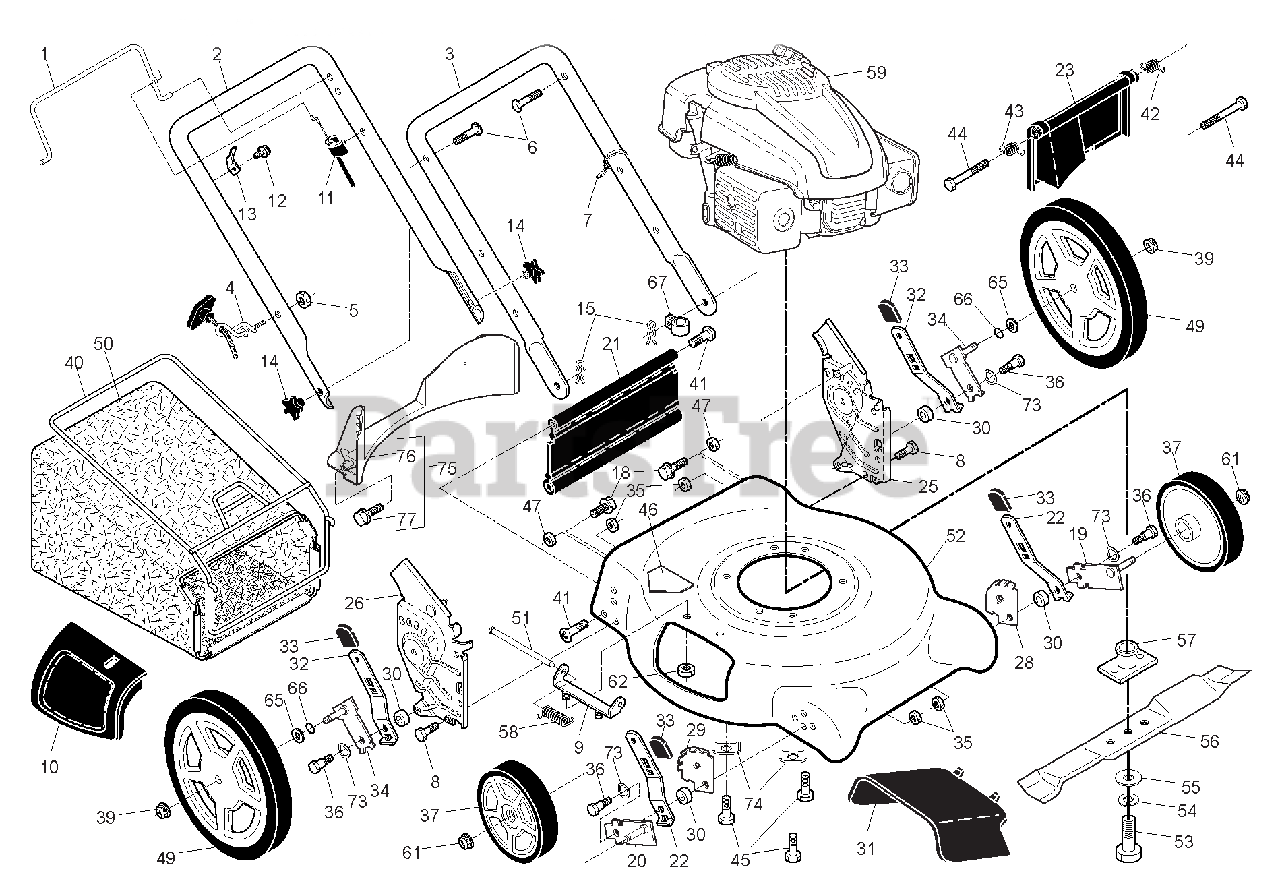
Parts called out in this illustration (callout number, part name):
1	Control Bar
2	Upper Handle
3	Lower Handle
4	Rope Guide
5	Nut, Hex
6	Handle Bolt
7	Wire Tie
8	Bolt, Hex Head 5/16-18 x 3/4
9	Hinge Bracket
10	Mulcher Door
11	Engine Zone Control Cable
12	Hex Washer Head Screw
13	UP-STOP BRACKET
14	Handle Knob
15	Hairpin Cotter
18	SCREW.HEX.WASHEAD.1/4-20 X 3/8
19	Axle Arm Assembly, Front, LH
20	Axle Arm Assembly, Front, RH
21	Kit, Rear Skirt
22	Selector Spring, Front
23	Rear Door Assembly
25	Handle Bracket Assembly, LH
26	Handle Bracket Assembly, RH
28	Wheel Adjusting Bracket, LH
29	Wheel Adjusting Bracket, RH
31	Discharge Deflector
32	Selector Spring, Rear
33	Selector Knob
34	Axle Arm Assembly, Rear, LH
35	Locknut, Hex 5/16-18
36	Shoulder Bolt
37	Wheel & Tire Assembly, Front
39	Flanged Locknut, Hex
40	Frame, Grassbag
41	Hinge Screw
42	Spring, Rear Door, LH
43	Spring, Rear Door, RH
44	Bolt, Rear Door
45	Screw, Hex Head, Threaded, Rol
46	Danger Decal
47	Nut, Hex
48	Axle Arm Assembly, Rear, RH
49	Wheel & Tire Assembly, Rear
50	Grassbag
51	Hinge Rod
52	Kit, Lawn Mower Housing (Inclu
53	Screw, Hex Head, Grade 8 3/8-2
54	Helical Lockwasher
55	Hardened Washer
56	21" Blade
57	Blade Adapter
58	Hinge Spring
61	Nut, Hex
62	Locknut, Hex 1/4-20
65	Washer, Flat
67	Clip, Cable
73	Washer, Curved, Cylindrical
74	Washer, Special, Engine
75	Kit, Rear Baffle (Includes 3 S
76	Baffle, Rear
77	Screw, Rear Baffle
